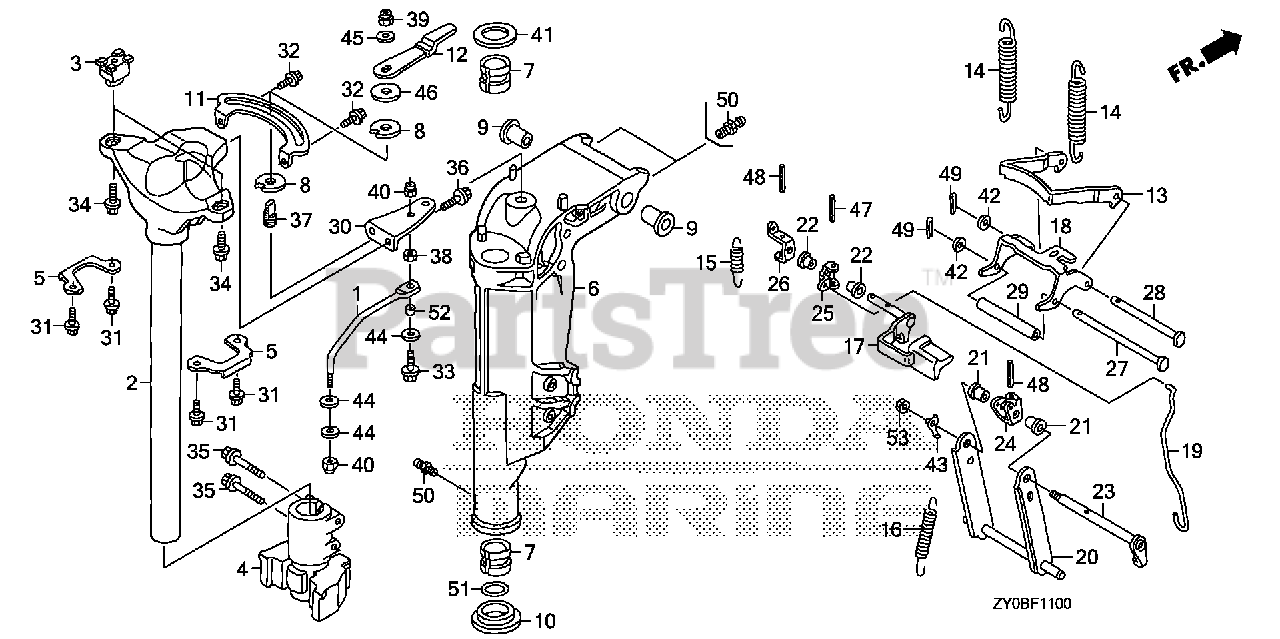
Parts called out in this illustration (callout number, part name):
2	FRAME, MOUNTING (S)
3	RUBBER, MOUNTING (UPPER)
4	RUBBER, MOUNTING (LOWER)
5	COVER, MOUNTING RUBBER (UPPER)
6	CASE, SWIVEL *NH282MU* (S) (OYSTER SILVER METALLIC-U)
7	LINER, SWIVEL CASE
8	BLOCK, FRICTION
9	BUSH, SWIVEL CASE
10	COLLAR, SWIVEL CASE
11	PLATE, FRICTION
12	LEVER, FRICTION
13	HOOK, REVERSE LOCK
14	SPRING, REVERSE LOCK
15	SPRING, TILT LEVER
16	SPRING, TILT LINK
17	LEVER, TILT
18	ARM, REVERSE LOCK
19	ROD, RELEASE SWIVEL CASE
20	ARM, TILT
21	BUSH, TILT LEVER
22	BUSH, TILT LEVER
23	SHAFT, TILT
24	BRACKET, TILT SHAFT
25	BRACKET, RELEASE ROD
26	BRACKET, TILT LEVER
27	SHAFT, REVERSE LOCK (A)
28	SHAFT, REVERSE LOCK (B)
29	COLLAR, REVERSE LOCK
31	BOLT, FLANGE (6X12) Use from Frame SN 1005249.
32	BOLT, FLANGE (6X12)
34	BOLT, FLANGE (10X25)
35	BOLT, FLANGE (8X45)
37	BOLT, STUD (8X26)
39	NUT, SELF-LOCK (8MM)
41	WASHER, THRUST
42	WASHER, PLAIN (6MM) Use from Frame SN 4800713.
43	WASHER, LOCK
45	WASHER (8MM)
46	WASHER, NYLON (8MM)
47	PIN, SPRING (3.0X22)
48	PIN, SPRING (3.0X25)
49	PIN, SPLIT (2.0)
50	NIPPLE, GREASE
51	O-RING (34X2.4)
53	NUT, HEX. (6MM)
